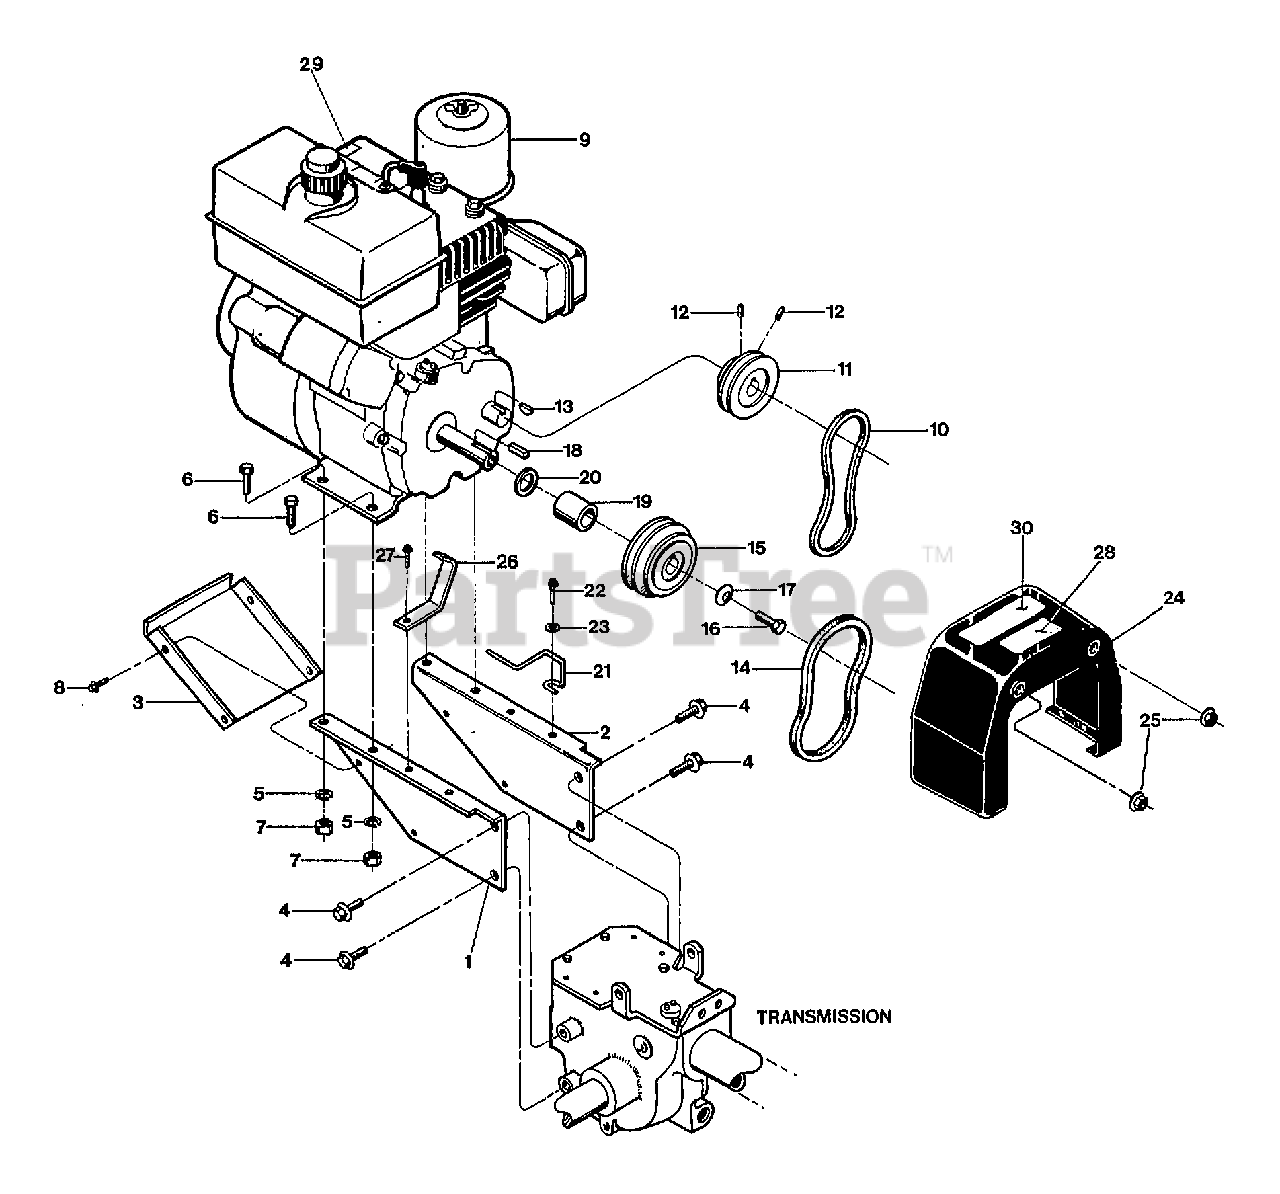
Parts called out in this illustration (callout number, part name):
1	BRKT-ENG LT P4
2	BRKT-ENG RT PNT
3	PAN-ENG BRKT PNT
4	SCR-HFLK 5/16-18X.75 ZP
5	WASHER-LK .312 ZP
6	SCR-HHC 5/16-18X.75 GR 5 ZP
7	NUT-HEX 5/16-18 ZP
8	SCR-HW M10-32X.5 THRD ROLL
9	ENGINE, TECUMSEH, 6HP RECOIL START,
10	BELT-V REV DR ECONO (SEE V-BELT BELOW)
11	PULLEY-REV MACH
12	SCR-SS 1/4-20 X .25 (SECURES REVERSE ENGINE PULLEY)
13	KEY-WOODRUFF #5
14	BELT-V GROOVE FWD SMFRAME
15	PULLEY-ENGINE MACH
16	SCR-HH 3/8-24X1.0 G5 ZP
17	WASHER-.994X.413X.145
18	KEY-.188 SQX1.0
19	SPACER-.937X.755X.938
20	SHIM-1.0X.7656X.031
21	GUIDE-BELT FWD
22	SCR-HWH 1/4-20 X .75 STH
23	WASHER-FLAT 1/4 SAE
24	COVER-BELT W/DECALS (INCL. 28 & 30)
25	NUT-HFLK 5/16-18 ZP
26	GUIDE-BELT REV PNT
27	SCR-HWH 1/4-20 X .5 STH
28	DECAL-BELT POSITION
29	DECAL-STARTING STABIL
30	DECAL-BELT COVER OPC
